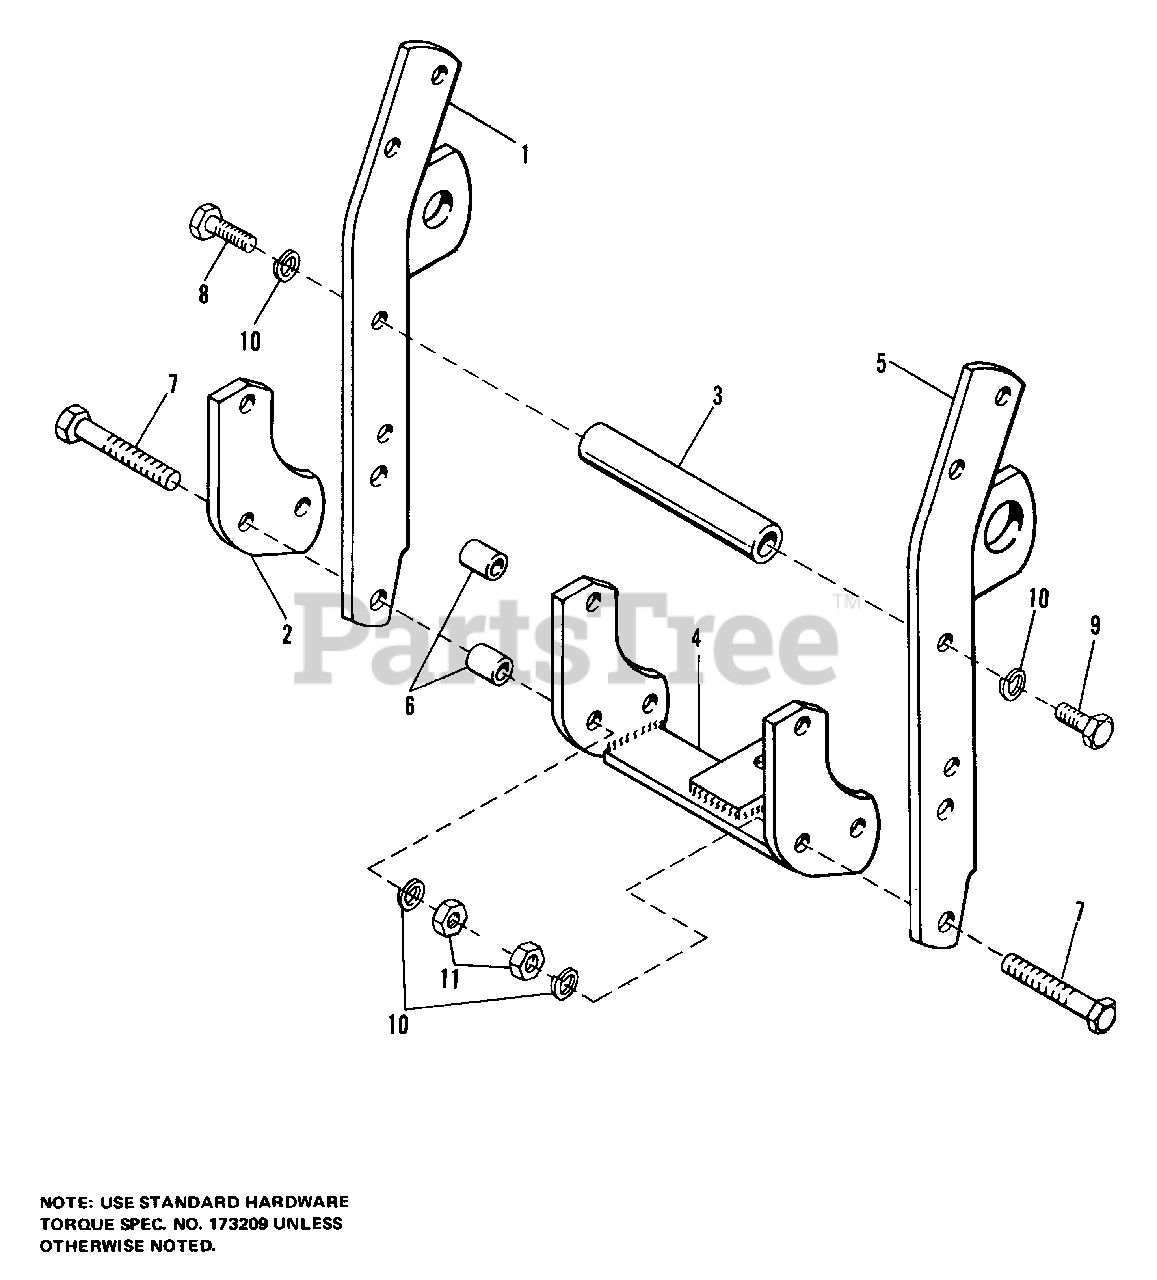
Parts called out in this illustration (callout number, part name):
1	BRAKE ASSY, Upright
4	BAR ASSY, Draw
5	BAR ASSY, Upright
7	CAPSCREW, Hex, 7/16-14 x 2-3/4
8	CAPSCREW, Hex, 7/16-14 x 1-3/4
9	CAPSCREW, Hex, 7/16-14 x 1-1/4
10	LOCKWASHER, 7/16
11	NUT, Hex, 7/16-14
